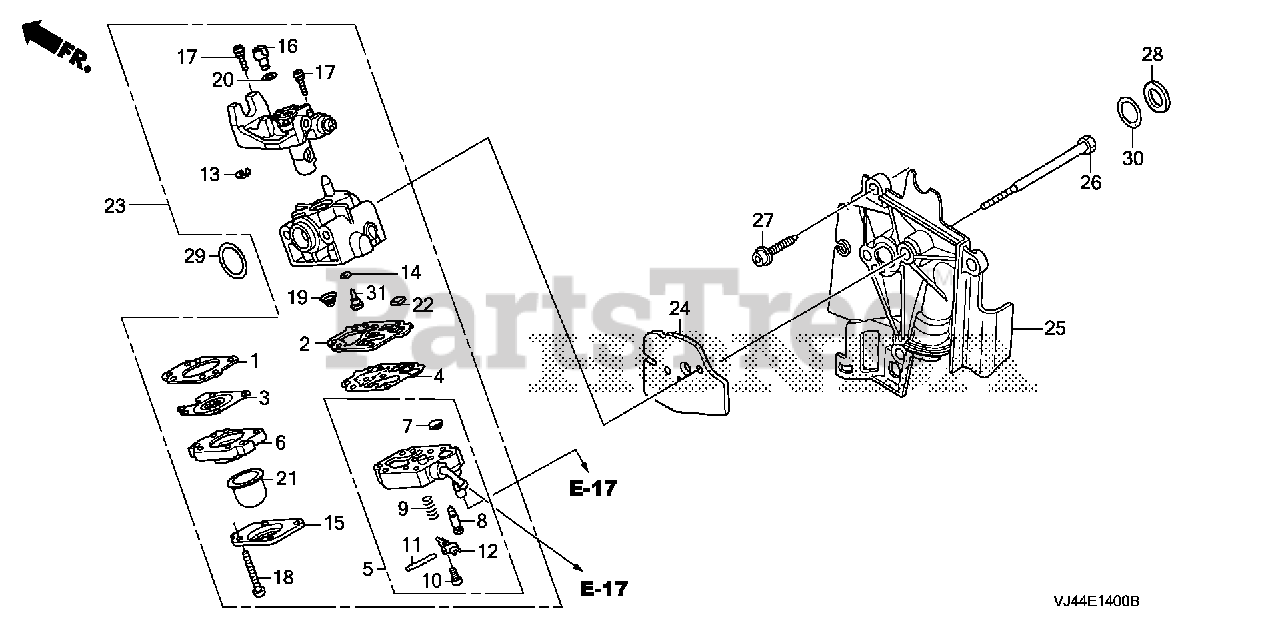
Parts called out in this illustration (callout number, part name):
1	GASKET, METERING DIAPHRAGM
2	GASKET, PUMP (CARBURETOR NO.)
3	DIAPHRAGM ASSY., METERING
4	DIAPHRAGM, PUMP
5	BODY ASSY., PUMP (CARBURETOR NO.)
6	BODY ASSY., AIR PURGE
7	SCREEN, INLET
8	VALVE, INLET NEEDLE
9	SPRING, METERING LEVER
10	SCREW, METERING LEVER PIN
11	PIN, METERING LEVER (CARBURETOR NO.)
12	LEVER, METERING
13	RING, RETAINING
15	COVER, PRIMER PUMP
17	SCREW, THROTTLE COLLAR
18	SCREW, PUMP COVER
19	SPRING, PUMP
21	PUMP, PRIMER
22	FILTER, FUEL INLET
23	CARBURETOR ASSY. (WYB 6F)
23	CARBURETOR ASSY. (WYB 34)
23	CARBURETOR ASSY. (WYB 34A/B)
24	GASKET, CARBURETOR
25	SHROUD
26	BOLT (5X53)
27	BOLT, SOCKET (5X16)
29	O-RING (14.8X2.4)
30	O-RING (12.3X2.4) (CARBURETOR NO.)
31	JET (#33)
31	JET (#32)
